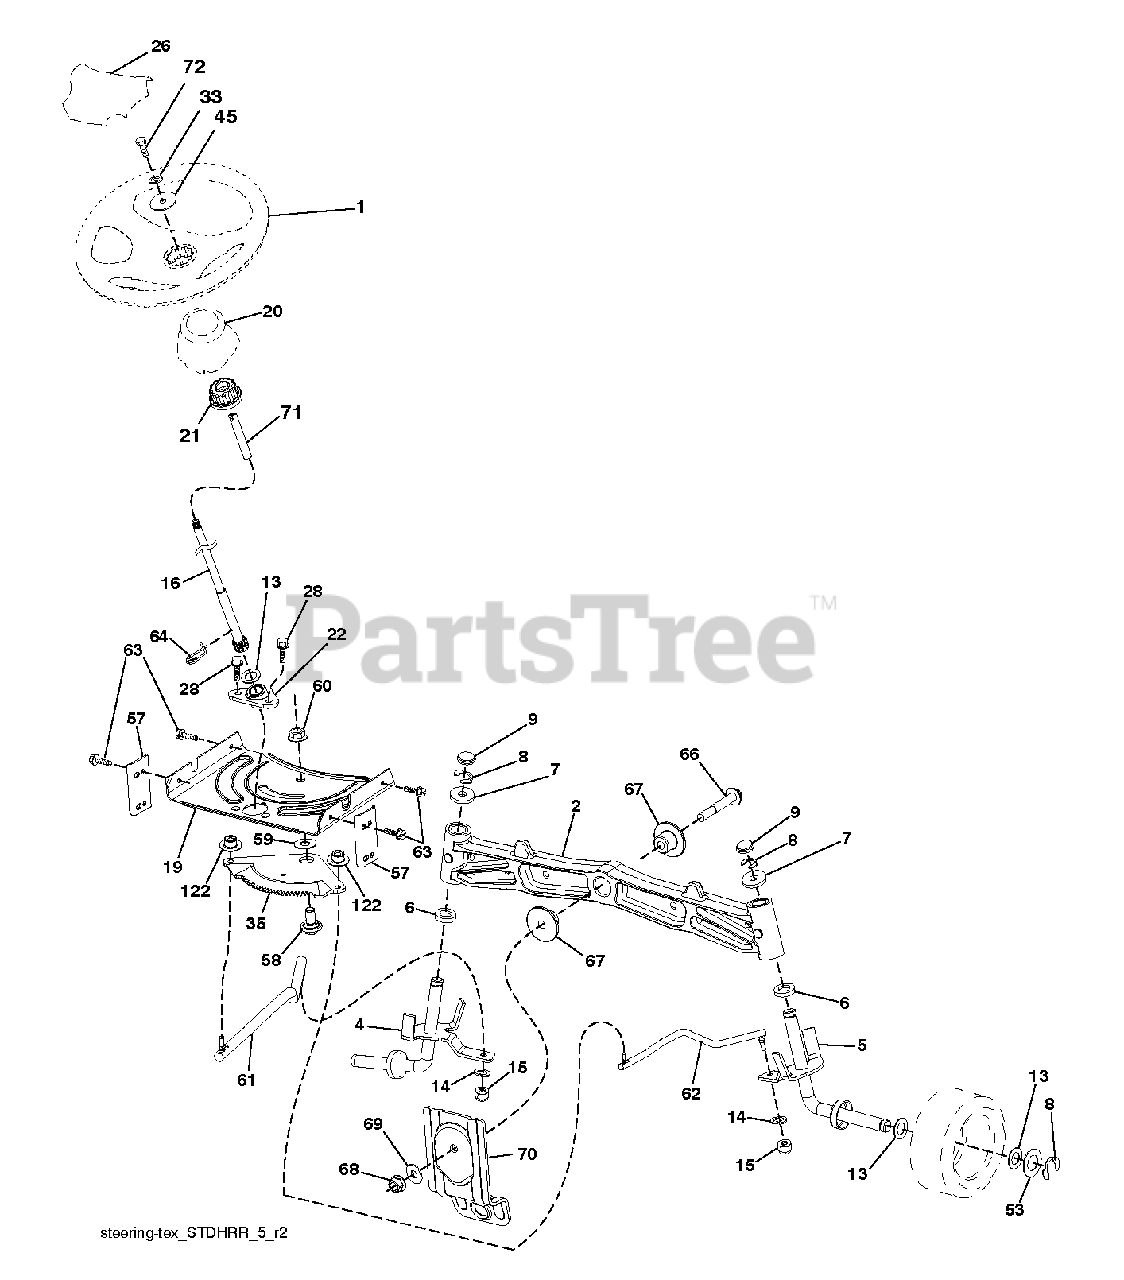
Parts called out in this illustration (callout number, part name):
1	WHEEL.STEERING.HUSQ.PREM.HRDRM
2	AXLE.CAST.IRON
4	SPINDLE.WELDED.LH.15"TEX
5	SPINDLE.WELDED.RH.15"T
6	THRUST WASHER
9	CAP.SPINDLE.BLACK
14	WASHER, LOCK 3/8
15	NUT CROWNLOCK 3/8-24
16	SHAFT.STEER.3/4.NON-PLATED.TEX
19	PLATE.STEER.DDL.NLT/NG
20	STEERING.BOOT.HUSQ.LT
21	ADAPTER, WHEEL STNG..
22	STEERING.SUPT.LOWER.
26	INSERT.CAP.WHL.STRG.HUSQ.PREM
28	SCREW, 3/8-16X3/4
33	LOCKWASHER
35	GEAR.SECTOR.PLATE.DDL.
45	WASHER.11/32
53	WASHER.HARDENED
57	BRACKET.UPSTOP.TEX
58	BOLT.SHOULDER.SECTOR.P
59	WASHER.THURST.SECTOR.S
60	NUT FLANGE LOCK 5/8-11
61	DRAGLINK.LH.BALLSTUD.D
62	DRAGLINK.RH.BALLSTUD.D
63	SCREW
64	RETAINER.CLIP.SPRING.S
66	BOLT HEX FGHD 7/16-14 X 3 SERR
67	BUSHING.PM.FRONT AXLE
68	NUT.LOCK.FLANGE.7/16
69	WASHER.1.5X.505X.118
70	BRKT.DECK.SUSPENSION.F
71	SHAFT.EXTEN.STRG.SPLINE
72	BOLT 5/16-18 X 4 W/PATCH
122	CAP.GEAR.SECTOR.TEX
